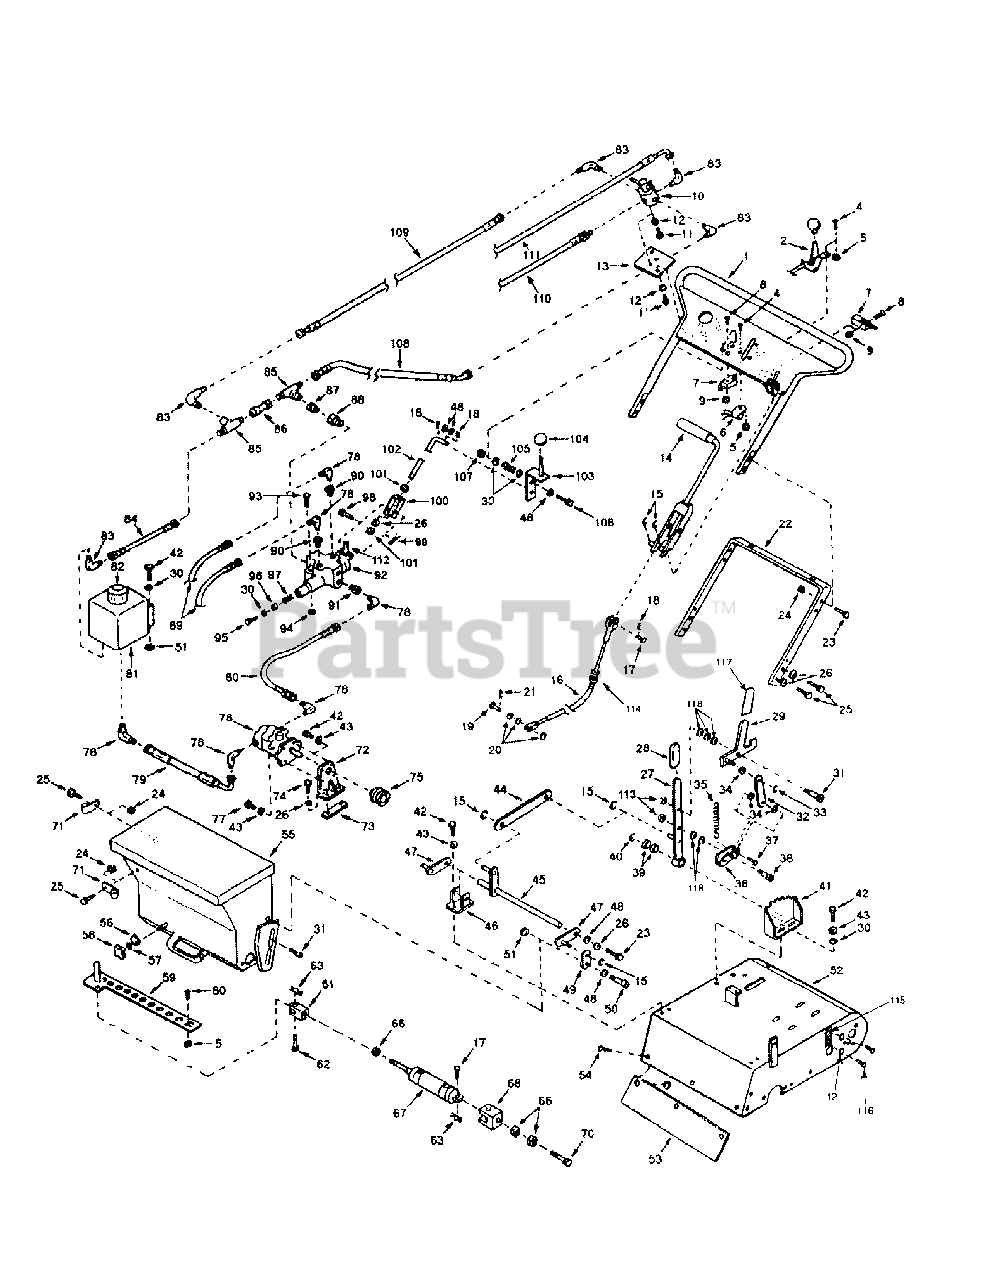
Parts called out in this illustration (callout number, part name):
1	Upper Handle
2	Throttle
4	Mach. Screw, #10-32 x 1/2 Phil. Rd. Hd.
5	Hex Nut, #10-32 Nylock
6	Sensor, Volt, Module
7	Safety Switch
8	Mach. Screw, #5-40 x 3/4 Rd. Hd
9	Hex Nut, #5-40
10	Selector Valve
11	Cap Screw, 1/4-20 x 1/2
12	Lock Washer, 1/4
13	Mounting Plate, Valve
14	Handle, Blade Clutch
14	Grip, Blade Clutch Handle
15	E-Ring
16	Control Cable, Blade Clutch
17	Clevis Pin, 5/16 x 1-5/8
18	Cotter Pin, 1/8 x 3/4
19	Clevis Pin, 3/16 x 3/4
20	Flat Washer, 3/16
21	Cotter Pin, 1/16 x 1/2
22	Lower Handle
23	Cap Screw, 3/8-16 x 1 Hex Hd
24	Hex Nut, 3/8-16 Nylock
25	Cap Screw, 3/8-16 x 3/4 Hex Hd
26	Lock Washer, 3/8
27	Handle, Hopper Lift
28	Grip,1/4 x 1 x 4
29	Pivot, Hopper Lift
30	Flat Washer, 5/16 USS
31	Shoulder Bolt, 3/8 x 3/8 Soc. Hd
32	Short Link
33	E-Ring
34	Flat Washer, 1/4 Nylon
35	Tension Spring
36	Latch
37	Clevis Pin, 1/4 x 3/4
38	Shoulder Bolt, 3/8 x 5/8 Soc. Hd
39	Bushing
40	E-Ring
41	Bracket, Hopper Lift
42	Cap Screw, 5/16-18 x 3/4 Hex Hd
43	Lock Washer, 5/16
44	Long Link
45	Rod, Hopper Lift
46	Support, Hopper Lift
47	Arm, Hopper Lift
48	Flat Washer, 3/8 SAE
49	Link, Hopper Lift
50	Shoulder Bolt, 3/8 x 1/2 Soc. Hd
51	Hex Nut, 5/16-18 Nylock
52	Power Deck
53	Brush Guard
54	Rivet w/Washer
55	Hopper w/Cover
56	Dial, Seed Flow Adjustment
57	Flat Washer, 1/4
59	Metering Bar
60	Mach. Screw, #1 0-32 x 5/8 Phil. Rd. Hd.
61	Clevis, Cylinder
62	Clevis Pin, 5/16 x 1
63	Hairpin, 3/8 - 1/2
65	Splice, Clip
66	Jam, Hex Nut, 3/8-24
67	Cylinder, Seed Flow
68	Yoke, Cylinder Mount
70	Cap Screw, 3/8-24 x 1-1/4 Hex Hd
71	Support Clamp, 3/4
72	Pump Mount
73	Nut Bar, Pump
74	Cap Screw, 3/8-16 x 1-1/4 Hex Hd
75	Pulley, Pump Drive
76	Hydraulic Pump
77	Cap Screw, 5/16-18 x 1 Hex Hd
78	Hydraulic Fitting, 90° Elbow
79	Hydraulic Hose, Tank to Pump
80	Hydraulic Hose, Pump to Valve
81	Tank, Hydraulic Oil
82	Fill Cap, Hydraulic Oil Tank
83	Hydraulic Fitting, 90° Elbow
84	Hydraulic Hose, Return to Tank
85	Hydraulic Fitting, Tee
86	Hydraulic Valve, Pressure Relief
87	Hydraulic Fitting, Reducer
88	Hydraulic Fitting, Reducer
89	Hydraulic Hose, Valve to Hyd. Motor
90	Hydraulic Fitting, Reducer
91	Hydraulic Fitting, Reducer
92	Hydraulic Valve
93	Cap Screw, 1/4-20 x 1-1/2 Soc. Hd
94	Hex Nut, 1/4-20 Nylock
95	Cap Screw, 5/16-18 x 2 Hex Hd
96	Spacer
97	Spring
98	Clevis Pin, 3/16 x 1-1/4
99	Hairpin, 5/16 - 3/8
100	Shift Clevis
101	Hex Nut, 3/8-24
102	Rod, Shift Lever
103	Lever, Direction Control
104	Black Knob
105	Compression Spring
106	Cap Screw, 3/8-16 x 2 Hex Hd
107	Hex Nut, 3/8-16
108	Hydraulic Hose, Valve to Valve
109	Hydraulic Hose, Valve to Return
110	Hydraulic Hose, Cylinder Open
111	Hydraulic Hose, Cylinder Close
112	Valve Handle
113	Acorn Nut, 5/16-18
114	Split Nut
115	Anchor, Cable Assembly
116	Hex, Cap Screw, 1/4-20, .75
117	Grip, 3.5 Yellow, Operator
118	Flat Washer, Nylon, 3/8"
